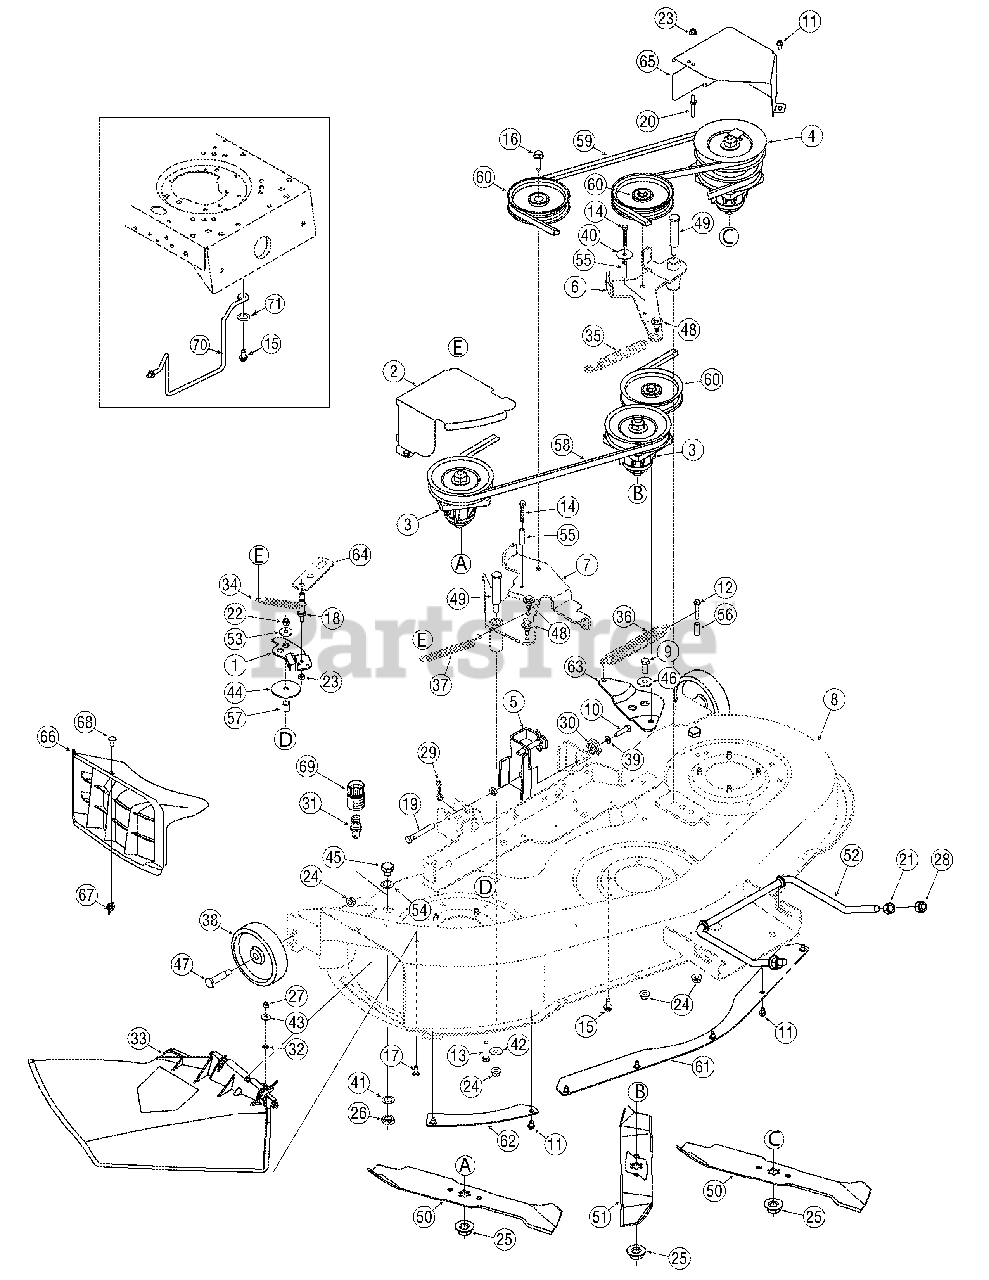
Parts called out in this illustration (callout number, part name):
1	Brake Assembly, Deck
3	Spindle Assembly, 5.00 Dia.
4	Spindle Ass’y, Double Pulley
9	Screw, 3/8-16, 1.00, Gr5
10	Screw, 5/16-18, 1.25, Gr5
11	Screw, 1/4-20, 0.500
12	Screw, 1/4-20, 1.500
13	Screw, 5/16-18, 1.50, Gr5
14	Screw, 1/4-20 x 1.75
15	Screw, Ld, 5/16-18, 0.750
16	Screw, 3/8-16 x 1.250
17	Screw, 1/4-20, .75, Gr5
18	Pin, 1/4-20, 3/8 x 2.0
19	Clevis Pin, 3/8 x 2.75
20	Belt Guard Pin 1/4 Dia x 1.43
21	Nut, Hex, 1/2-13, Gr5
22	Nut, Flange Lock, 5/16-18, GrF
23	Nut, Flange Lock, 1/4-20, GrF
24	Nut, Flange Lock, 3/8-16, GrF
25	Nut, Flange, 5/8-18
26	Nut, Hex, M16-1.5
27	Nut, Hex, 1/4-20, Gr5
28	Nut, Hex Lock, 1/2-13
29	Bow Tie Cotter Pin 1/8 x 1.25
30	Adjustment Gear, Deck
31	Water Nozzle Adapter
32	Nut, Push, .25 ID x .50 OD
33	Chute Assembly
34	Spring, Extension, .50 x 3.97
35	Spring, Extension, .75 x 6.835
36	Spring, Extension, .91 x 7.33
37	Spring, Extension, .56 x 5.52
38	Wheel, Deck 5.0 x 1.38
39	Washer, Lock, 5/16
40	Washer, Flat, .285 x 1.25 x .06
41	Washer, Lock, 5/8
42	Washer, Flat, .385 x 1.0 x .135
43	Washer, Bell, .265 x.75 x .062
44	Washer, Flat, .34 x 2.25 x.10
46	Spacer, Shoulder, .625 ID x .169
47	Spacer, Shoulder, .498 x 1.53
48	Shld, Screw, .43 x .29, 5/16-18
49	Shld. Screw, .625 x 2.515 x .875
50	Blade, 16.28", Star 3-in-One
51	Blade, 14.88", Star 3-in-One
52	Rod, Deck Adjustment
53	Shoulder Spacer
54	Washer, Flat, .64 x 1.24 x .06
55	Spacer, .260 x .372 x 1.420 Lg.
56	Spacer, .260 x .372 x 1.030
57	Spacer, .375 x .63 x .595
58	Belt, V-Type, Poly, A x 79.10 Lg.
59	Belt, V-Type, A x 90.24
60	Pulley, Idler, 4.25" Dia.
66	Mulch Plug
67	Wing Nut
68	Carriage Screw, 1/4-20 x .62
69	Deck Water Nozzle
70	Belt-Keeper Rod
71	Washer, Flat, .406 x .875 x .059
72	Sems Screw, 3/8-16 x 1.500
73	Idler Belt-Keeper Rod
17258E-0606	COVER:BELT:DECK 46 - MAJESTIC ORANGE (0606)
17258E-0637	Deck Belt Cover, 46" Black - POWDER BLACK (0637)
17258E-0650	COVER:BELT:DECK 46 - RED METALLIC (0650)
17258E-0665	COVER:BELT:DECK 46 - YARDMAN GREEN (0665)
17258E-0691	COVER:BELT:DECK 46 - BLACK JACK (0691)
17258E-4008	COVER:BELT:DECK 46 - WINE RED (4008)
